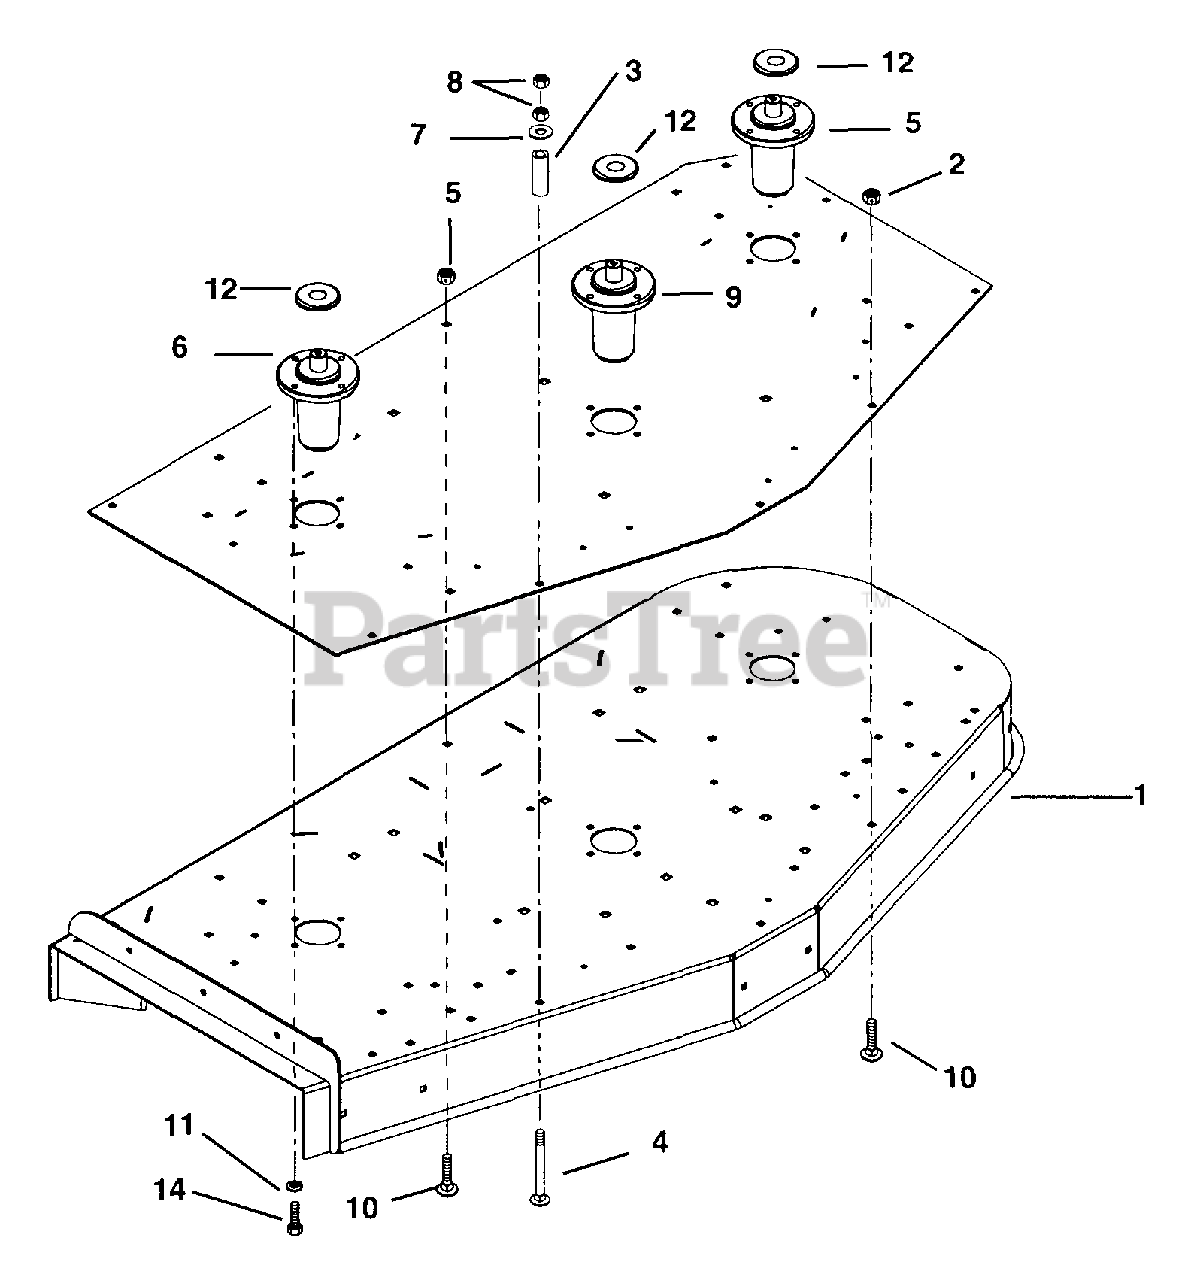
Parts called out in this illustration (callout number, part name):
1	Weldment, 72" Deck (Side Discharge)
2	Plate, 72" Reinforcment
3	Spacer .38 x .625 x 1.50
4	Bolt-Round Head Square Neck .38-16 x 2.75 Grade 5
5	Nut-Locking-Nylon .38-16
6	Assembly, Spindle L-Hub
7	Washer-Flat-Steel .406 x .812 x .065
8	Nut-Locking-Center .38-16
9	Assembly, Spindle
10	Bolt-Round Head Square Neck .38-16 x 1.00 Grade 2
11	Washer-Locking .38 x .094
12	Slinger-Dust
13	Ring, Retaining-Internal 2.210 x .062
14	Bolt-Hex .38-16 x 1.00 Grade 5
